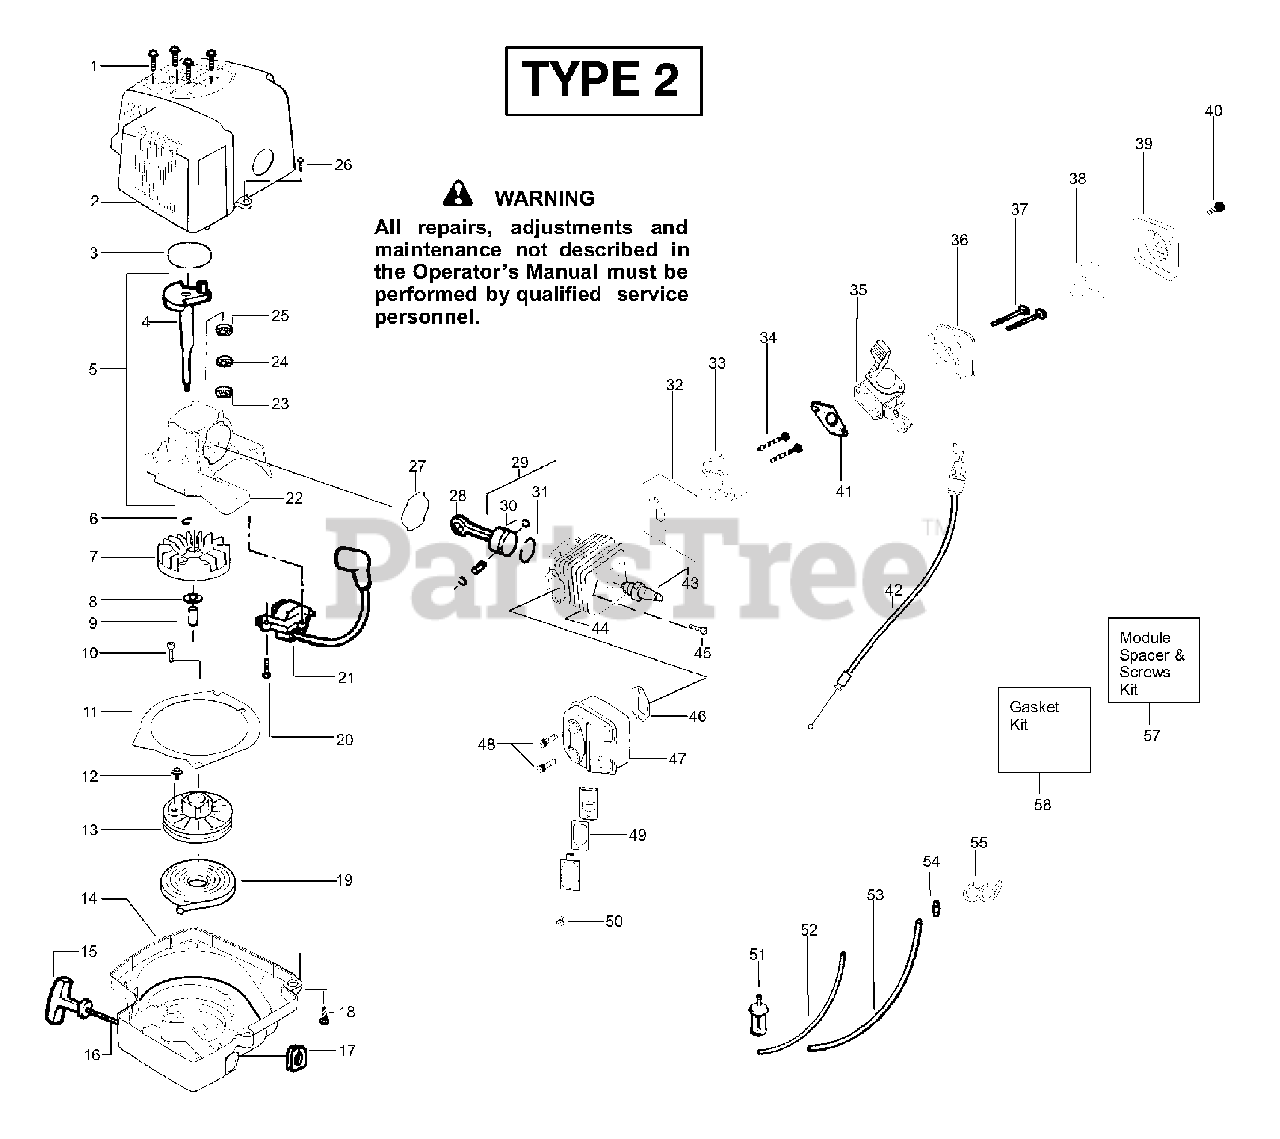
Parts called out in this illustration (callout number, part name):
2	Assy-Shroud/H'shield
3	O-Ring-C'case (kit)
4	Assy-Crankshaft
5	Assy-C/case-C/shaft
6	Ring-Retainer-C'shaft
7	Assy-Flywheel
8	Washer-Flat
9	Spacer-Flywheel
11	Plate-Baffle
13	Kit-Starter Pulley
14	Assy-Fan Housing
15	Handle-Starter
16	Kit-Rope
17	Grommet-Ignition Module
18	Screw-(f/hsg to shrd)
19	Spring-Starter
21	Ignition Module
22	Assy-Crankcase
23	Bearing-Outer
24	Seal-Crankcase
25	Bearing-Inner
27	Seal-Cylinder (kit)
28	Assy-Connecting Rod
29	Kit-Piston
30	Retainer-Piston Pin
31	Ring-Piston
32	Gasket-Carb. Adapt. (kit)
33	Adapter-Carburetor
35	Kit-Carburetor Ass'y. (C1U-W13A)
38	Air Filter Foam
39	Air Filter Cover
41	Gasket-Carburetor (kit)
42	Assy-Throttle Cable
43	Spark Plug (RCJ-6Y)
44	Kit-Cylinder
46	Gasket-Muffler (kit)
47	Kit-Muffler
48	Bolt-Muffler
49	Kit-Spark Arrestor
50	Screw
51	Assy-Pick-up
52	Kit-Fuel Line (small)
53	Kit-Fuel Line (large)
54	Fitting-Fuel Line
55	Clip-Retainer
56	Kit-Gasket
57	Kit-Module Spacer & Screws
